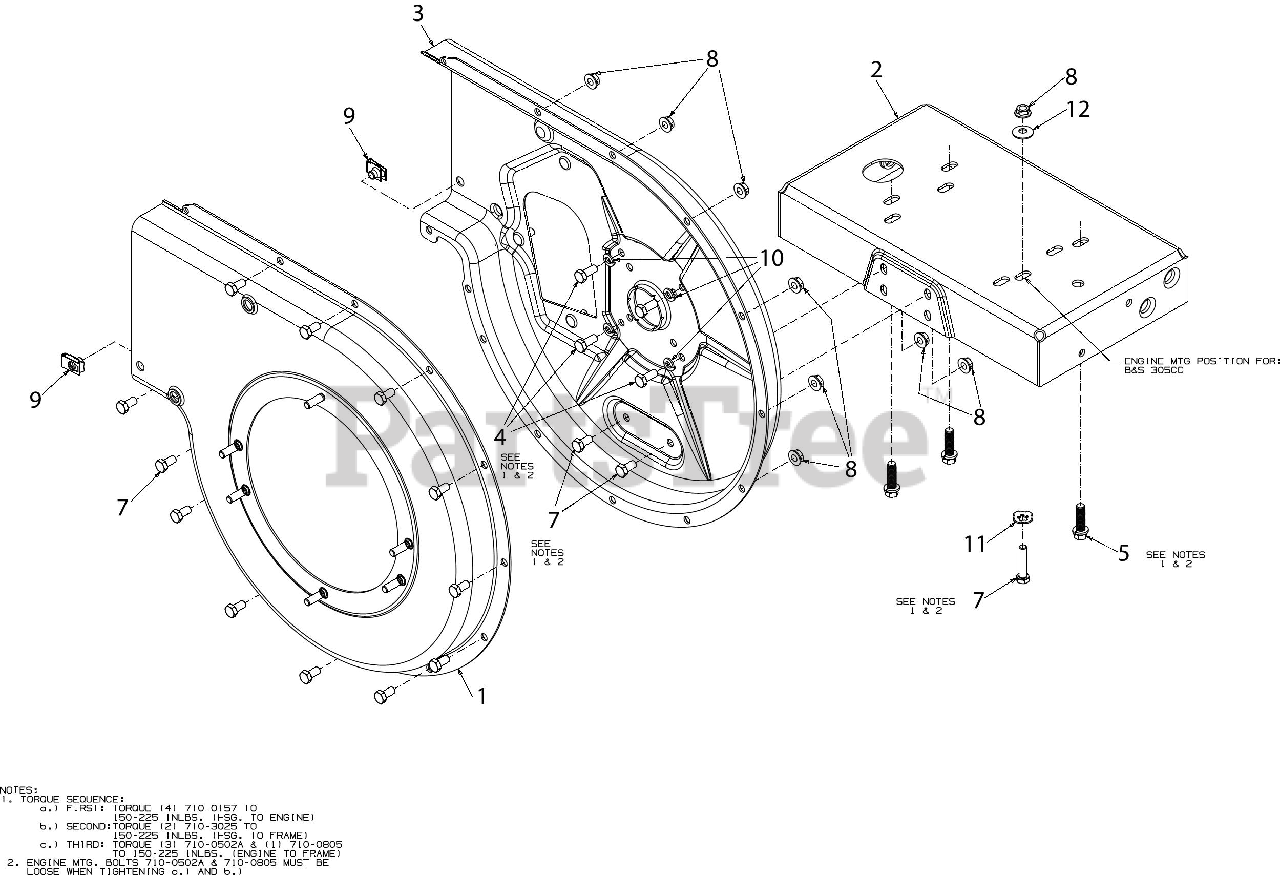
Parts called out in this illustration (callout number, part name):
1	FLAIL HOUSING ASSEMBLY (LH)
2	FRAME ASSEMBLY
4	HEX SCREW 5/16-24 x .75
5	SCREW 3/8-16 x 1.250
6	SCREW 5/16-18 x 1.5 LG
7	SCREW 5/16-18X .625 GR5
8	HEX FLANGE NUT
9	U-NUT
10	LOCK WASHER 5/16
11	SPECIAL WASHER
12	BELL WASHER .337 X.867 x .057
